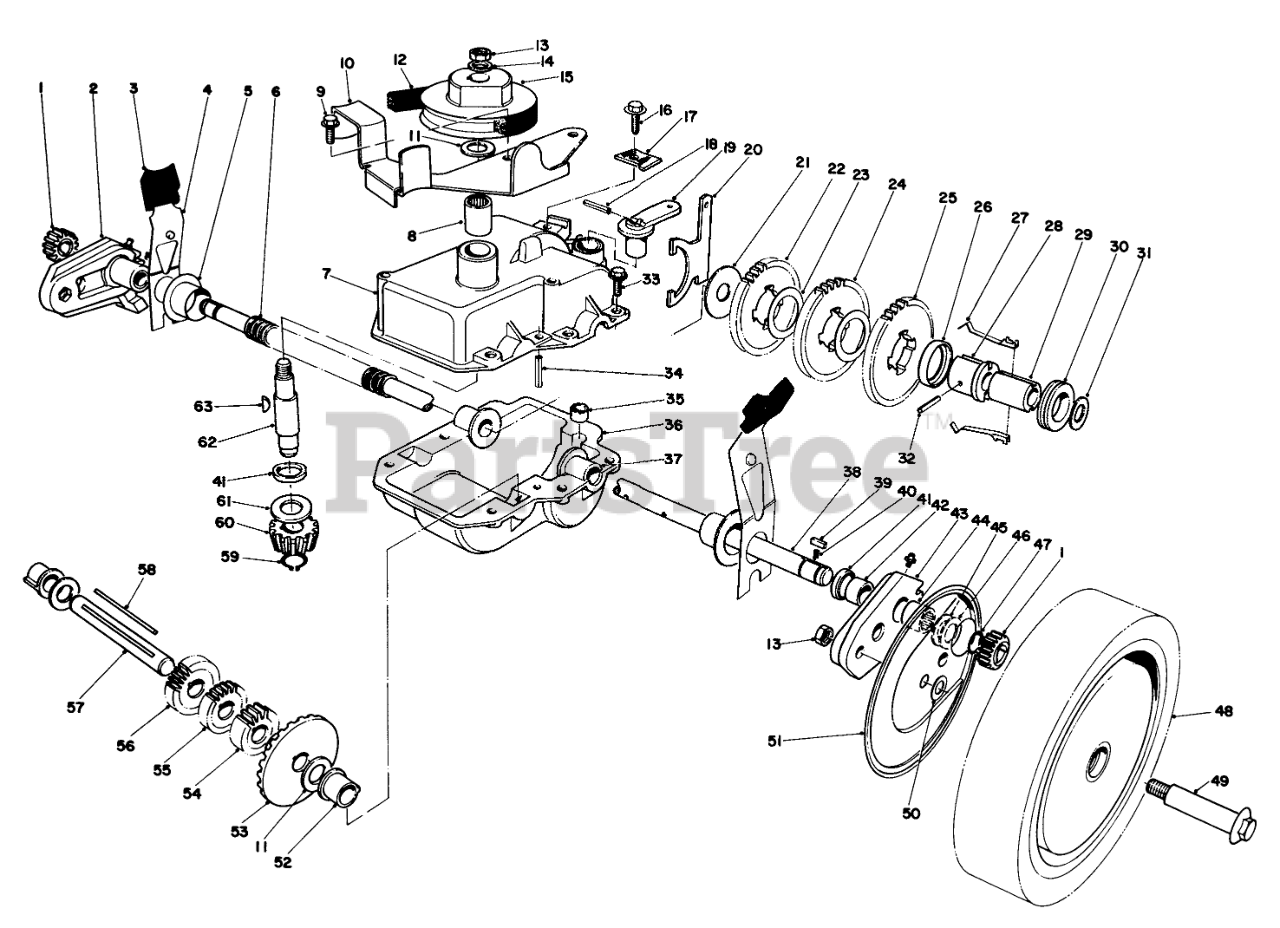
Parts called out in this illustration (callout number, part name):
1	GEAR-PINION
2	Pivot Arm Assembly-R.H. (Incl. Ref. #41, 42 & 44)
3	KNOB-ARM
4	SPRING ARM ASM SP
5	CAP-END
6	CONDUIT-CONVOLUTED, SPLIT
7	Case-Upper
8	Bearing
9	SCREW
10	Bracket-Belt Guide
11	Washer
12	V-BELT
13	Nut
14	Washer
15	PULLEY
16	SCREW-HWHTF
17	Cable Clamp
18	PIN-COIL
19	LEVER-SHIFT
20	9520 Shift Yoke
21	WASHER
22	Gear-38T
23	Washer
24	GEAR-42T
26	KEY RETAINER
27	Key
28	Body-Sleeve
29	SLEEVE
30	COLLAR-SHIFT
31	Washer
32	PIN-SPRING
33	SCREW-HWH, THREAD ROLL
34	ROLL PIN 3/16 X 1 IN
35	BUSHING-YOKE
36	LOWER GEAR CASE CAST
37	Bushing-Output Shaft
38	Output Shaft
39	KEY RECTANGULAR
40	SPRING-COMPRESSION
41	Seal
42	0 Bushing
43	Pivot Arm Assembly-L.H. (Incl. Ref. #41, 42 & 44)
44	Needle Baring
45	Washer
46	THRUST WASHER
47	RING-RETAINING
48	Wheel, Tire & Gear Assembly
49	BOLT-WHEEL
50	WASHER
51	WHEEL COVER
52	BUSHING
53	BEVEL GEAR
54	GEAR-12T
55	GEAR-14T
56	GEAR-18T
57	INTERMEDIATE SHAFT
58	Key Square
59	RING-RETAINING
60	PINION-BEVEL
61	Thrust Washer
62	INPUT SHAFT
63	KEY-WOODRUFF
